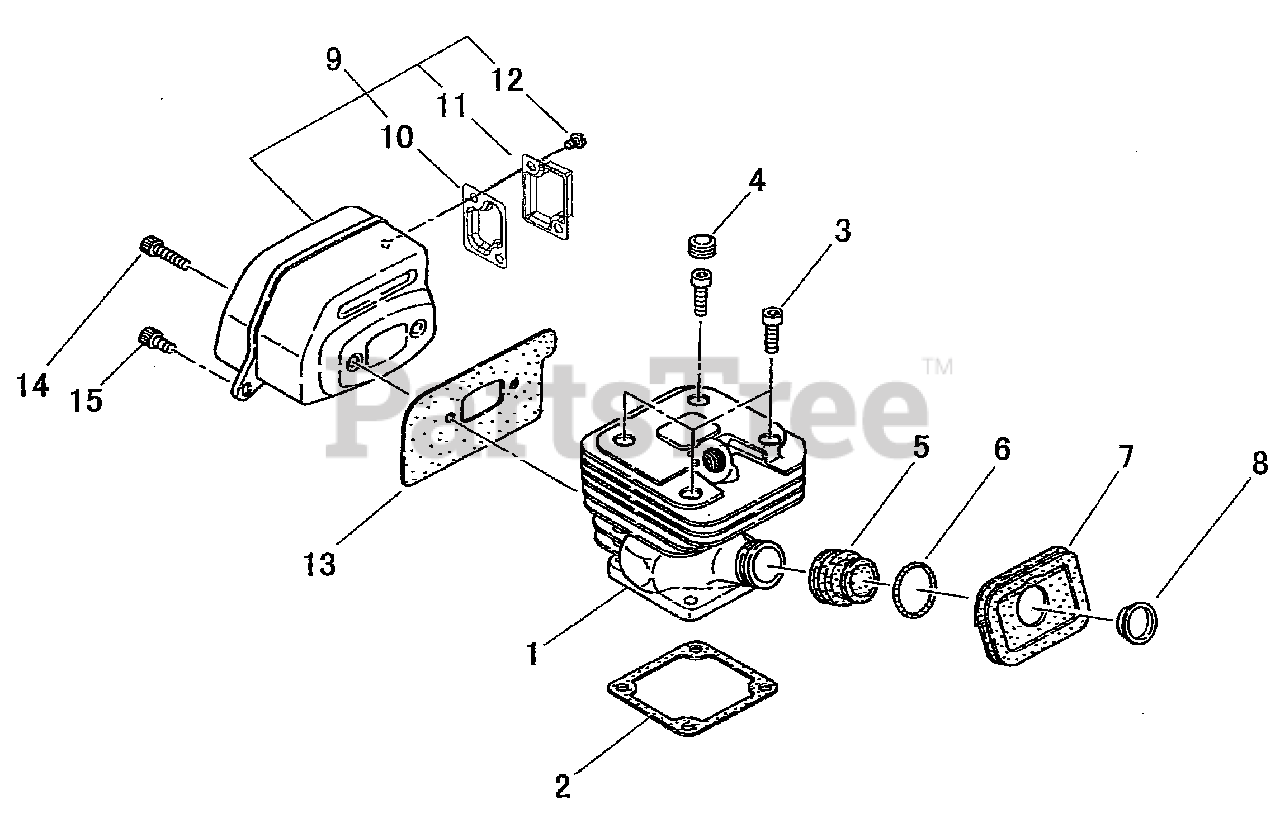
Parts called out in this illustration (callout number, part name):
1	CYLINDER
2	GASKET, CYLINDER
3	BOLT - 5X18
4	PLUG
5	BOOT
6	SPRING
7	SEAL
8	SLEEVE
9	MUFFLER ASSY
10	SCREEN, SPARK ARRESTOR
11	GUIDE, EXHAUST
12	SCREW - 4X6
13	GASKET
14	BOLT - 5X18
15	BOLT
